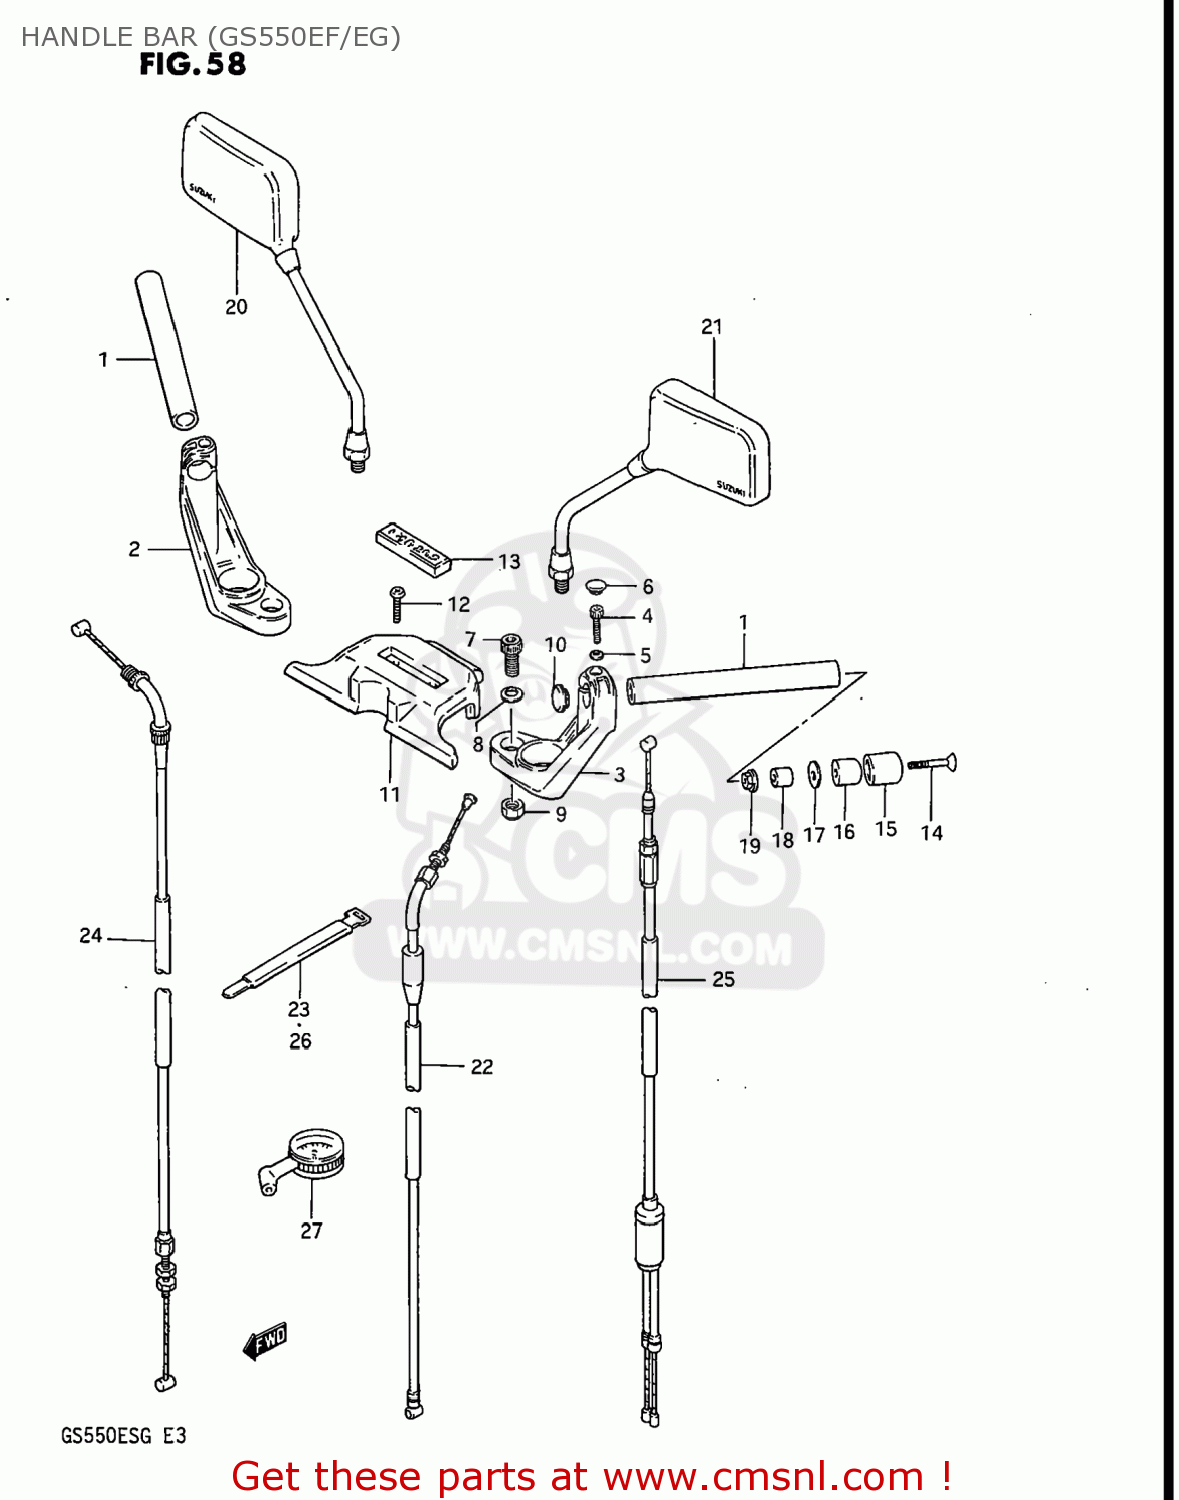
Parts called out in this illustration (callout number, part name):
1	HANDLEBAR
2	HOLDER,HANDLEBAR,RIGHT
3	HOLDER,HANDLEBAR,LEFT
4	BOLT 8X35
5	WASHER
6	CAP(OD:14.5)
7	BOLT(10X50)
8	WASHER
9	NUT
10	CAP,GRIP END
11	PAD,HANDLEBAR
12	SCREW
13	EMBLEM,HANDLE PAD
14	SCREW 6X55
15	CAP,BALANCER
16	BALANCER,HANDLEBAR
17	SPACER,BALANCER
18	EXPANDER,HANDLE BALANCER
19	NUT
20	MIRROR ASSEMBLY,REAR VIEW
21	MIRROR ASSEMBLY,REAR VIEW
22	CABLE ASSY,CLUTCH
23	CLAMP
24	CABLE ASSY,THROTTLE
25	CABLE COMP,STARTER
26	CLAMP
27	GAUGE ASSY,AIR PRESSURE
